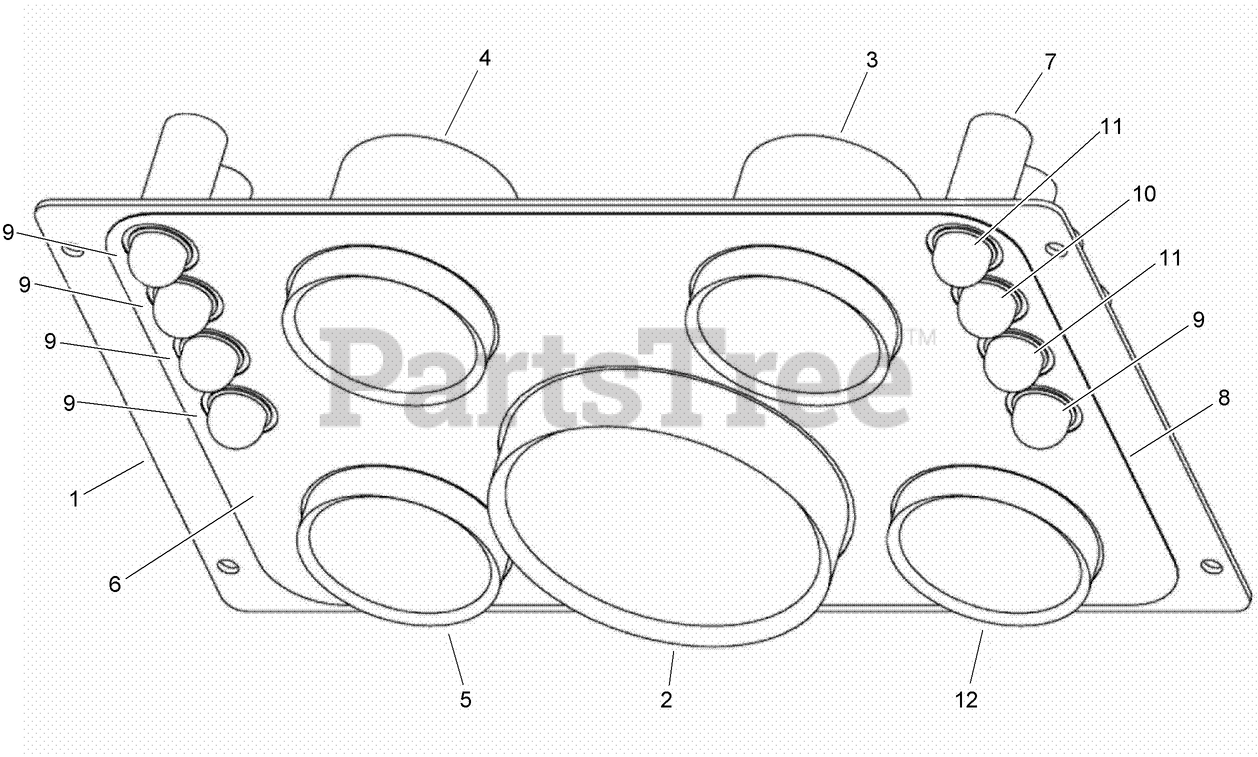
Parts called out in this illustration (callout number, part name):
1	PLATE-Mounting
2	GAUGE-Tachometer
3	GAUGE-FUEL
4	GAUGE-Volts
5	GAUGE-TEMP
6	OVERLAY-Decal
8	BULB-12 Volt
9	LENS-DOME, FLUTED AMBER (TYPE T2)
10	LENS-DOME, FLUTED GREEN (TYPE T2)
11	LENS-DOME, FLUTED RED (TYPE T-2)
12	GAUGE-HYD OIL TEMP
